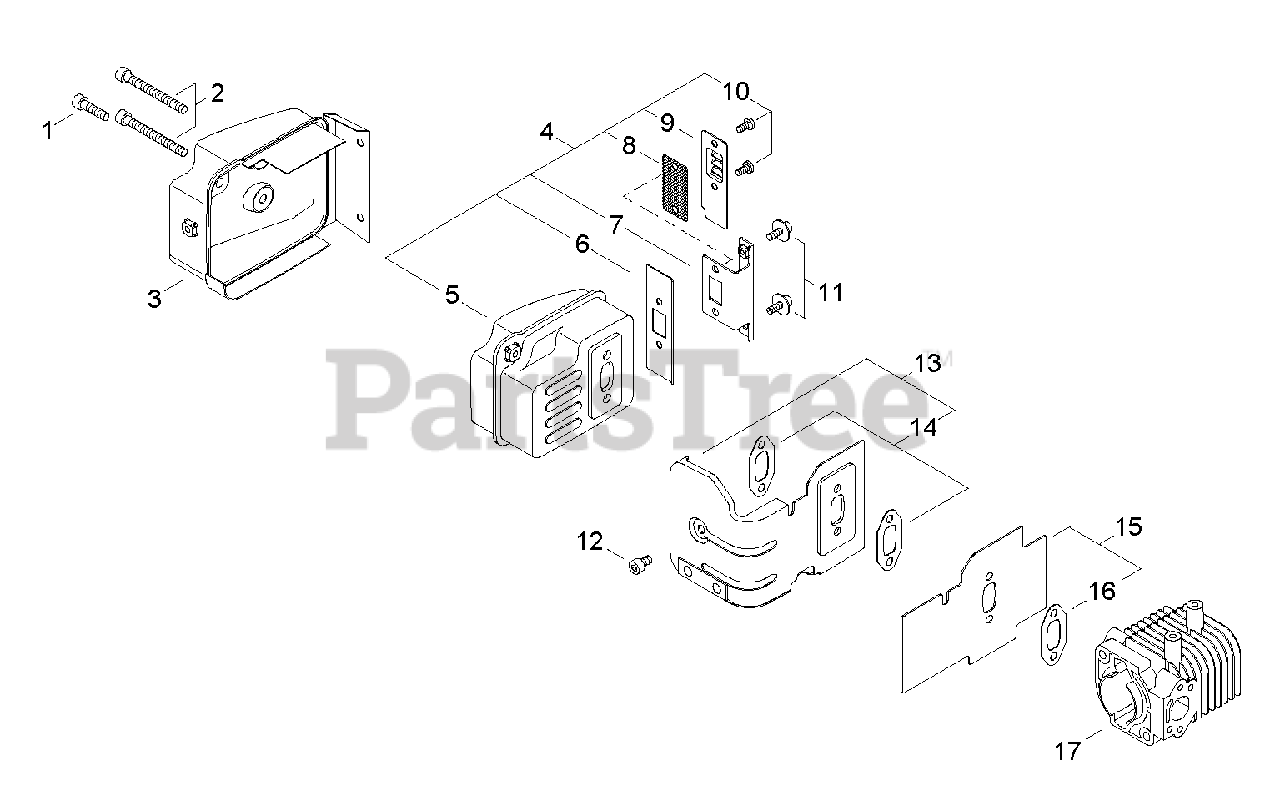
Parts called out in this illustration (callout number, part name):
1	BOLT CB-5×20
2	BOLT M5
3	COVER, MUFFLER
4	MUFFLER ASSY
5	MUFFLER
6	PLATE, MUFFLER
7	STAY, MUFFLER
8	SCREEN, SPARK ARRESTER
9	OUTLET, EXHAUST
10	SCREW 4×8
11	SCREW M4×8
12	BOLT 5×8
13	DEFLECTOR ASSY, EXHAUST HEAT
14	GASKET, EXHAUST
15	SHIELD ASSY, EXHAUST HEAT
16	GASKET, EXHAUST
17	CYLINDER
